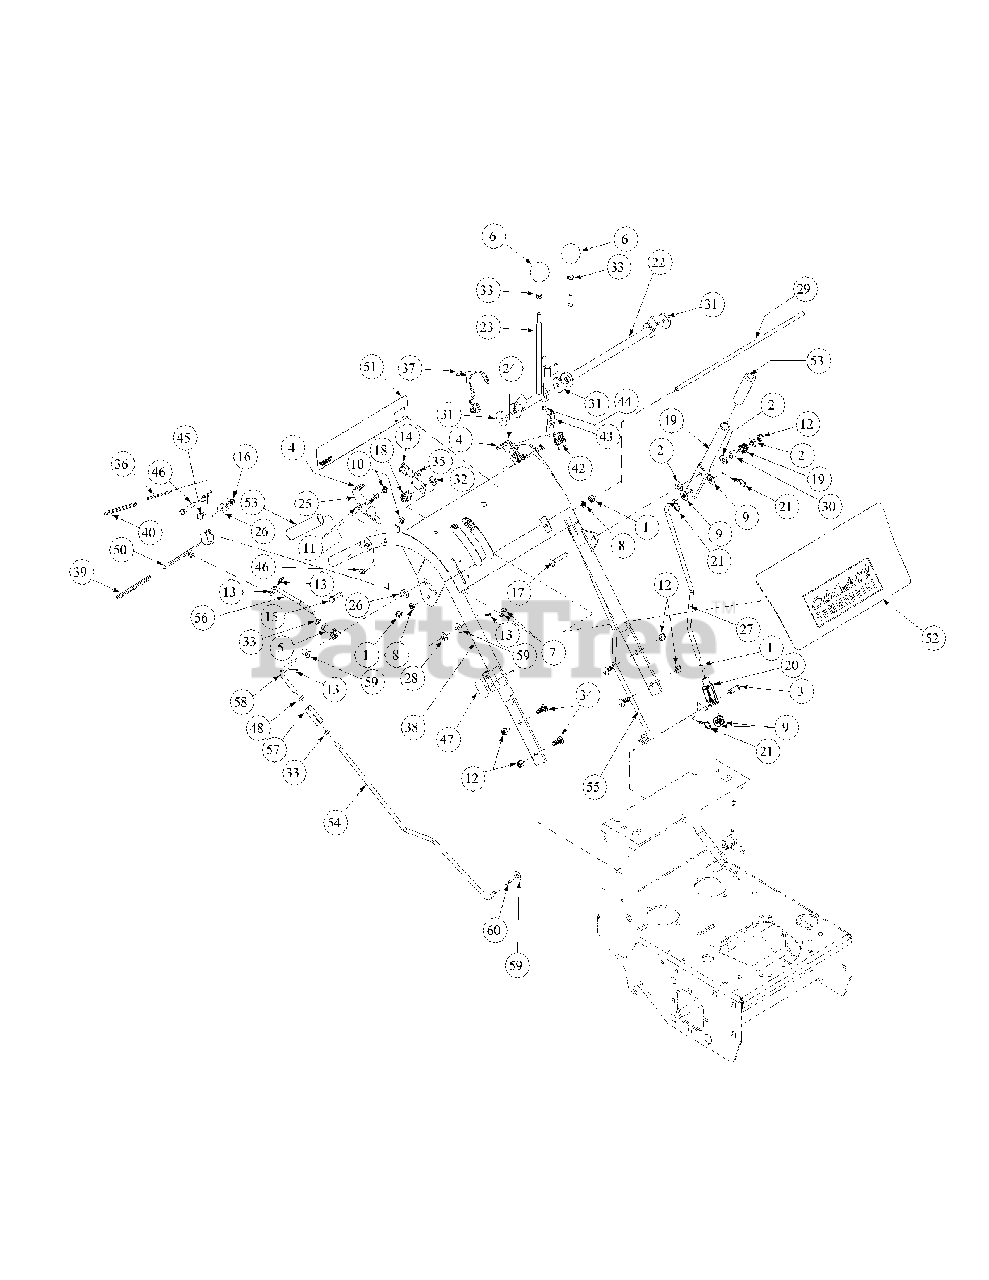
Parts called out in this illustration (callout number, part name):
1	Hex Nut, 3/8 - 16
2	Flat Washer, SS, 3/8
3	Clevis Pin, 3/8 x 1 1/8
4	Grip, 1.25, Black Neutral Lock
5	End Rod, 3/8
6	Knob, 1-3/8 x 1-19/64, 3/8-24
7	Lock Nut, Nylon Insert, 1/4-20
8	Lock Washer, 3/8 Zinc
9	Flat Washer, 3/8, SAE
10	Nut, 5/16-18
11	Flat Washer, SAE 5/16
12	Lock Nut, Nylon Insert, 3/8-16
13	Cotter Pin, 5/32 x 1-1/2 Zinc
14	HHCS, 1/4-20, .75
15	HHCS, Standard, 5/16-18 x 2
16	Lock Nut, Nylon Insert, 1/4 - 28
17	Carriage Bolt, 3/8 -16 x 2
18	Switch Operator's Presence
19	Spring, .850
20	Yoke, 3/8 - 16, Female
21	Hair Pin, 3/8 - 1/2
22	Control Assembly, Speed Hydro, LH
23	Control Assembly, Speed Hydro, RH
24	Latch, RH, Neutral Hydro
25	Latch, LH, Neutral Hydro
26	Hydro, Spacer Control Rod
27	Blade Clutch, Hydro Rod Base
28	Hydro Bush Control Rod
29	Hydro Rod, Speed Control
30	Sleeve Spring, 32/36/48
31	Friction Washer
32	Hex Nut, Dead Man Switch
33	Hex Jam Nut, 3/8-24
34	Carriage Bolt, 3/8 -16 x 2
35	Mounting Switch, Neutral, Safety
36	Operator Presence Control Handle, RH
37	Operator Presence Control Handle, LH
38	Hydro, Handle Assembly
39	Control Sleeve, Drive Black
40	Operators Control Sleeve, Yellow
41	Harness Adapter Assembly
42	Snap Mounting Switch
43	Retension Spring
44	Screw, TT, 10-24, .5
45	Shoulder Screw, .38 x .412, 1/4-28
46	HHCS, 5/16-18, 2.00
47	Parking Brake Decal
48	Left Hand Threaded Jam Nut, 3/8-24
49	Clutch Lever Blade
50	Control Lever Assembly
51	Lable Handle
52	Panel Label
53	Black Handle Thin Grip
54	Large Right Control Rod
55	Large Left Control Rod
56	Short Control Rod
57	Turnbuckle
58	Upper Control Rod
59	Flat Washer .406 ID x 1.00 OD
60	Cotter Pin Internal, .072 x 1.12
